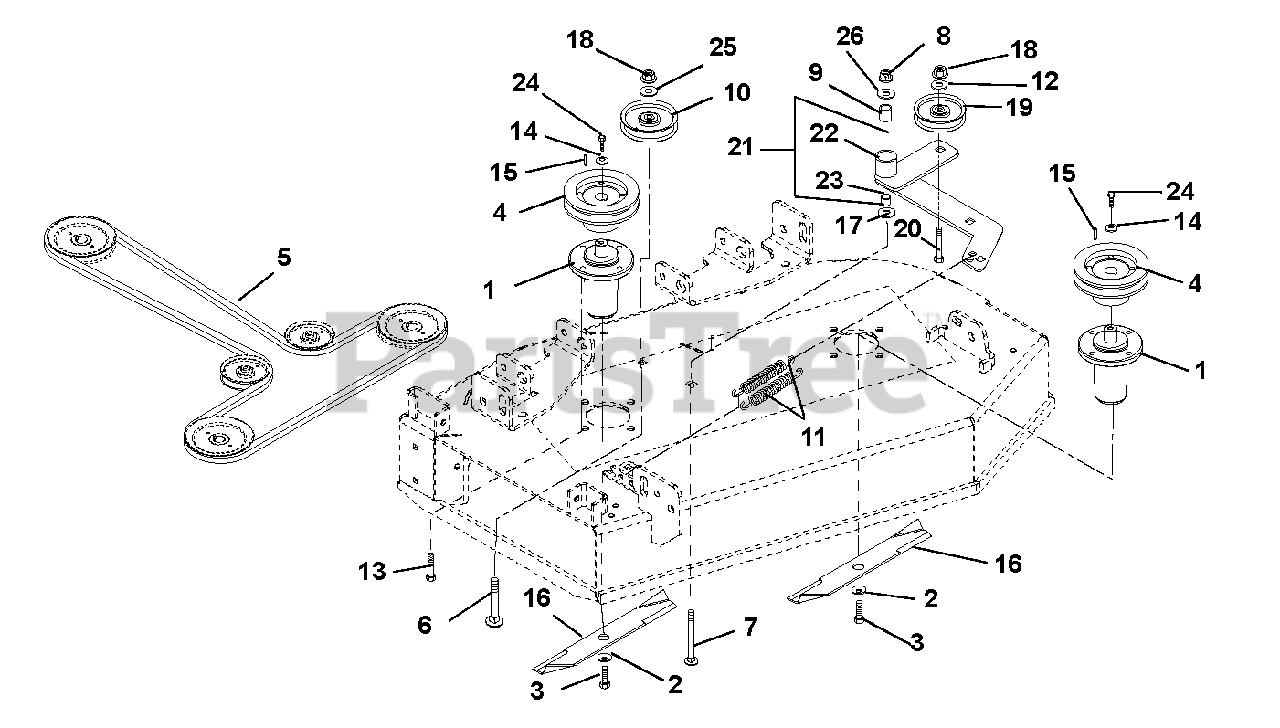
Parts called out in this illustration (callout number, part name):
1	Assembly, Spindle, Short
2	Washer, Bellville .63 x 1.625 x .14
3	Bolt, Hex .62-18 x 1.75 Grade 8
4	Sheave, 5.00 Spindle (1.00 I.D.)
5	V-Belt, B-Section 49.68 x .62548.80 x .625
6	Bolt, Round Head Square Neck .38-16 x 3.0
7	Bolt, Round Head Square Neck .50-13 x 3.50
8	Nut, Nyloc Flange .50-13
9	Bushing, Spacer .505/.500 x .999/.996 x 2.05/2.03
10	Idler, Flat 4.00 x .38 (2.00 W)
11	Spring, Extension
12	Washer, Flat Steel .375 x 1.125 x .065
13	Bolt, Hex .38-16 x 1.00 EP30
14	Retainer, Sheave
15	Key, Square .25 x .25 x .875
16	Blade, Mulching 50" Mower
17	Washer, Flat Steel .531 x 1.250 x .100
18	Nut, Nyloc Flange 3/8-16
19	Idler, Flat 4.00 x .38 (1.00 W)
20	Bolt, Round Head Square Neck .38-16 x 2.00
21	Assembly, Idler Pivot Arm (Contains Items 22 & 23)
22	Weldment, Idler Pivot Arm
23	Bushing, 1.00 x 1.125 x 1.936
24	Bolt, Hex .38-16 x 2.75 Grade 8
25	Seal, Idler Bearing
26	Washer, Flat Steel 511 x 1.441 x .125
